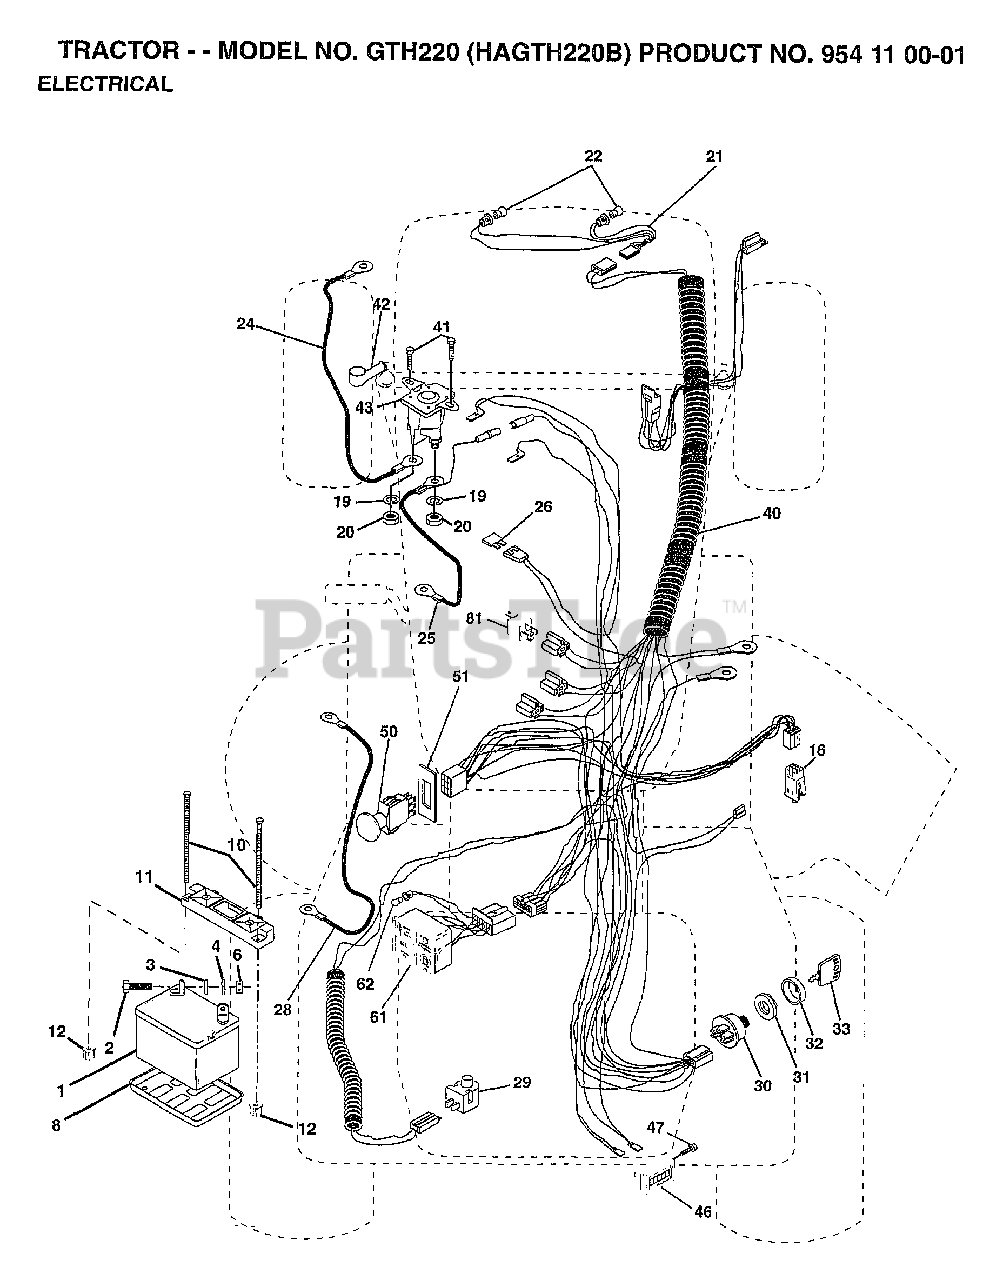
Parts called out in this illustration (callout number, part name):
2	BOLT HEX HD 1/4-20 X 3/4
3	WASHER, LOCK 1/4
4	WASHER 9/32 X 5/8 X 16 GA.
6	NUT, HEX 1/4-20
19	WASHER LOCK 1/4
20	NUT JAM HEX 1/4-20 UNC
40	IGNITION HARNESS
41	SCREW, 1/4-20 X 1/2
47	SCREW #10-24 X 1/2
